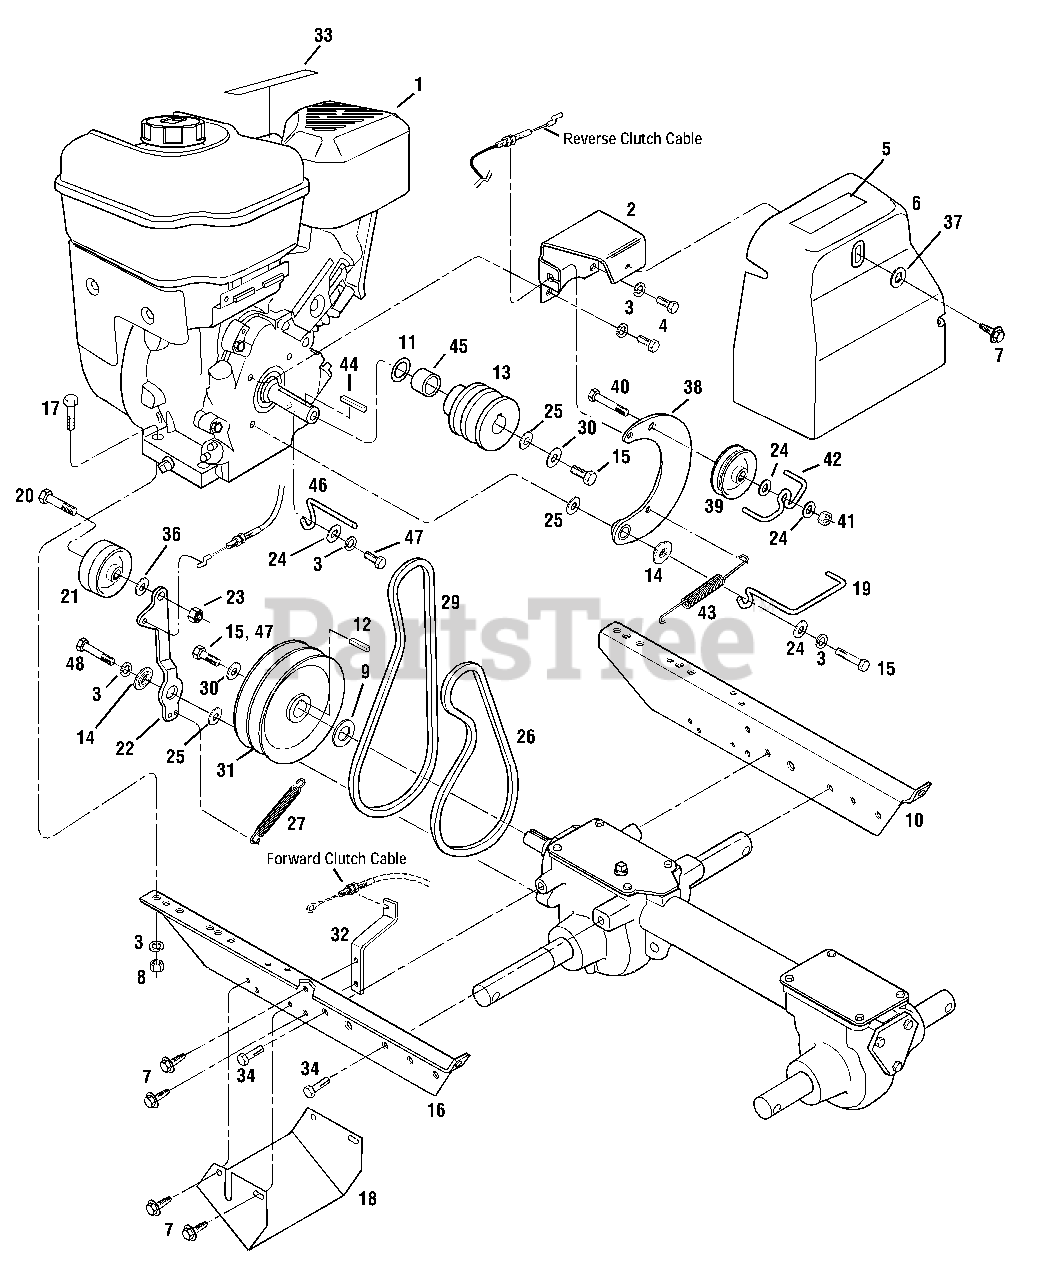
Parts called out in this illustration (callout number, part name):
1	Engine, Recoil Start
2	Bracket, Belt Cover
3	Lock Washer, 5/16
4	Hex Hd. Screw, 5/16-24 x 5/8
5	Decal, Hot Surfaces Warning
6	Belt Cover
7	Hex Hd. Flange Screw, Self-Tapping, 1/4-20 x 1/2
8	Hex Nut, 5/16-18
9	Support Washer
10	Engine Bracket, Right
11	Shim
12	Key, 3/16" x 1"
13	Pulley, Engine Drive
14	Shoulder Washer
15	Hex Hd. Screw, 5/16-24 x 1
16	Engine Bracket, Left
17	Hex Hd. Screw, 5/16-18 x 1-1/2
18	Guard, Belts/Pulleys
19	Forward Belt Guide
20	Hex Hd. Screw, 3/8-16 x 1-1/2
21	Forward Idler Pulley
22	Forward Idler Lever
23	Lock Nut, 3/8-16
24	Flat Washer
25	Flat Washer
26	Forward Drive Belt
27	Forward Return Spring
29	Reverse Drive Belt
30	Belleville Washer
31	Transmission Pulley
32	Bracket, Cable Mounting
33	Decal, Stabilization
34	Hex Hd. Screw, 5/16-18 x 5/8
36	Flat Washer, 3/8
37	Flat Washer
38	Reverse Idler Arm
39	Pulley, Reverse Idler
40	Hex Hd. Screw, 5/16-18 x 2
41	Lock Nut, 5/16-18
42	Belt Guide
43	Reverse Return Spring
44	Key, 3/16" x 1-1/2"
45	Spacer
46	Forward Belt Guide
47	Hex Hd. Screw, 5/16-24 x 3/4
48	Hex Hd. Screw, 5/16-18 x 1
